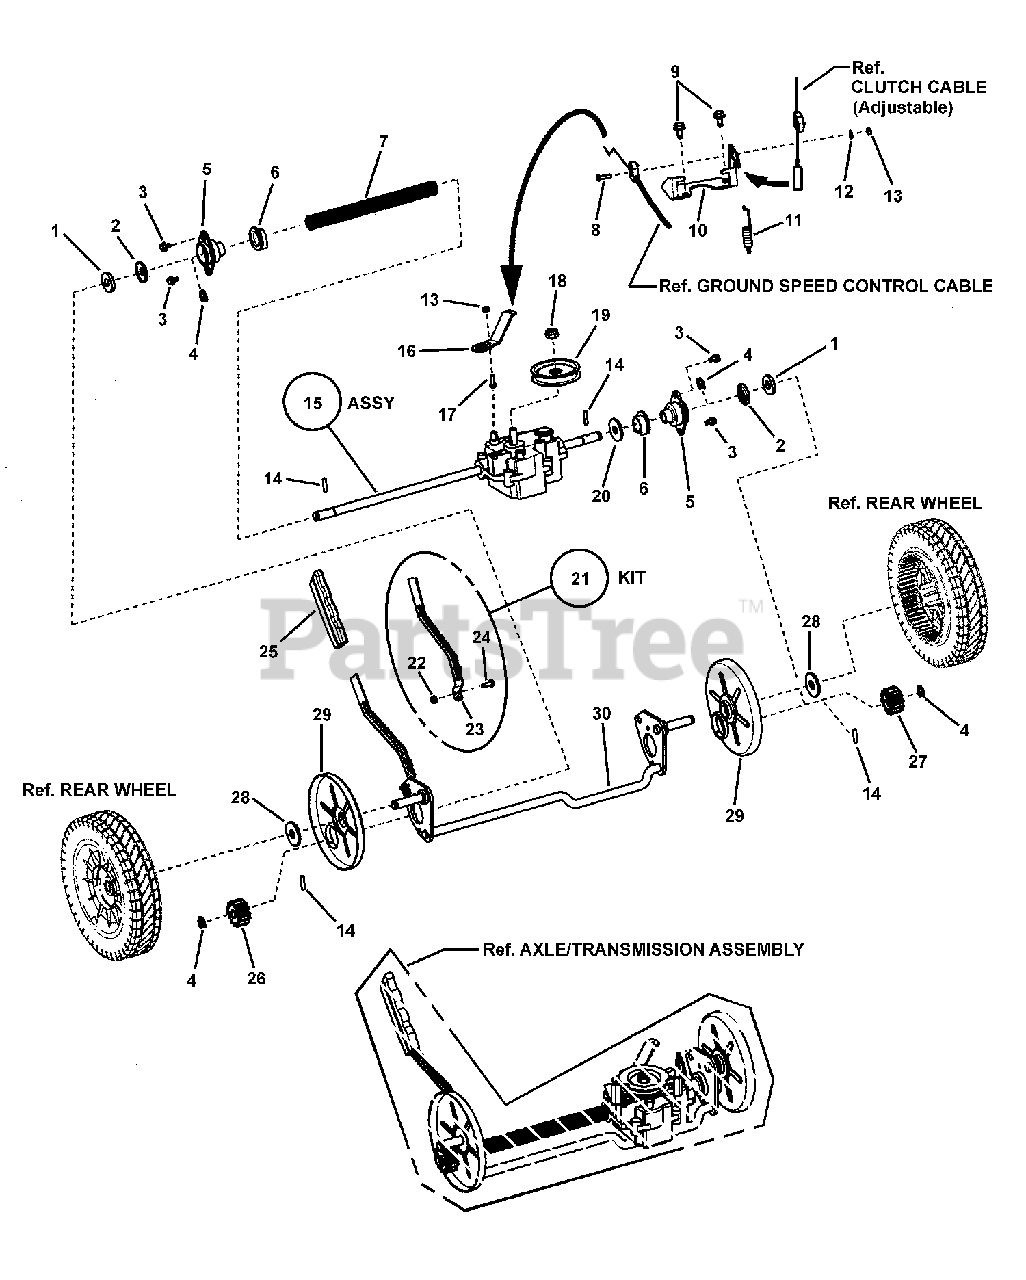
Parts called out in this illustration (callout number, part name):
1	SEAL, Pinion (Felt)
2	RETAINER, Pinion Seal
3	SCREW, 1/4-20 x 3/8" Hex Washer Head, Self-Tap
4	RING, External Retaining
5	ASSEMBLY, Bearing Carrier
6	BUSHING, Rear Axle (S/P)
7	TUBING, 5/8 I.D. Convoluted
8	SCREW, #10-24 x 3/4" Pan Head Machine
9	SCREW, 5/16-18 x 5/8" Hex Washer Head, Self-Tap
10	BRACKET, Transmission
11	SPRING, Clutch
12	WASHER, 7/32" Flat
13	* NUT, #10-24 Hex Center Lock
14	PAWL, 3/16" O.D.
15	TRANSMISSION ASSY, 3SP Commercial
16	* LEVER, Transmission (Metal)
17	* SCREW, #10-24 x 5/8" Slotted Hex Washer Head Self-Tap
18	NUT, M10 x 1.50 Hex Nyloc
19	PULLEY, Transmission
20	WASHER, Felt
21	KIT, Height Adjusting Lever (incl. items 22-24)
22	NUT, #10-32 Hex Nyloc
23	LEVER, Height Adjusting (Black)
24	SCREW, #10-32 x 5/8, Hex Washer Self-Tap, GR 5
25	GRIP, Flat Bar
26	PINION, RH Drive
27	PINION, LH Drive
28	WASHER, 17/32" Flat
29	SHIELD, Dust
30	WELDMENT, Rear Axle
